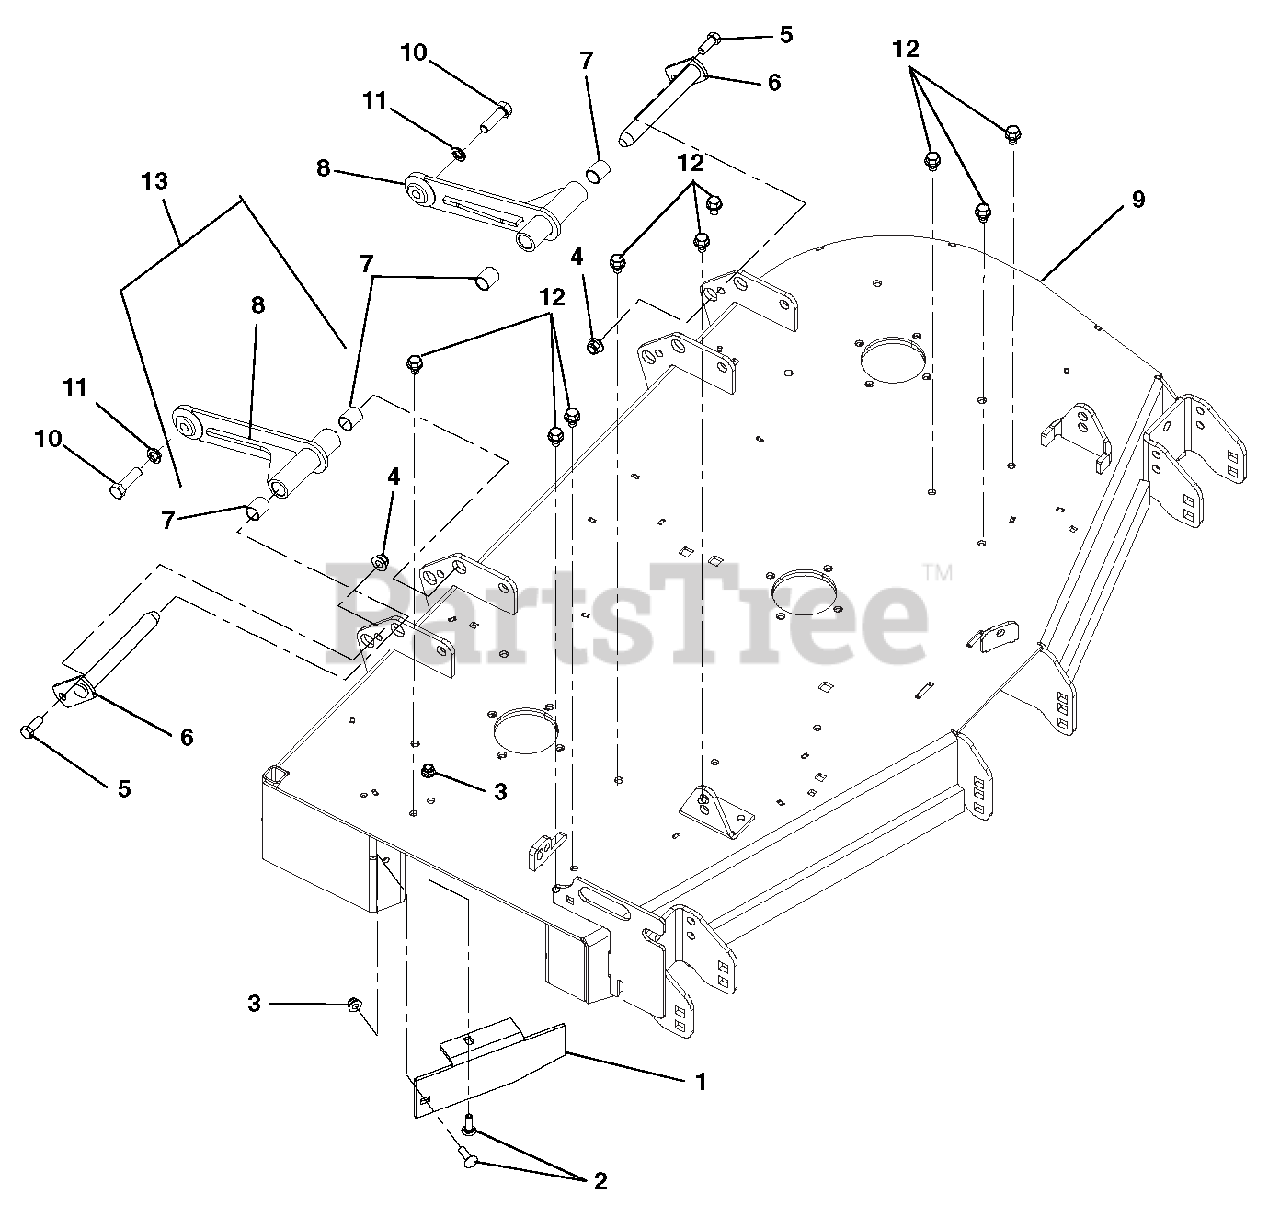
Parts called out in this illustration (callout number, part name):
1	44"-48" SIDE DISCH BAFFLE -RED
2	@BLT-RDHDSQNK .31-18X1.00 G5YZ
3	@NUT-LK-NYL-FLG .31-18 YWZC
4	@NUT-LK-NYL-FLG .38-16 YWZC
5	@BLT-HEX .38-16X1.00 GR5 YWZC
6	WELDMENT, MOWER MTG. PIN
7	BRG, .750 X .875 X 1.000
8	DECK PUSHER ARM WMT - BLACK
9	48" SIDE DISCHARGE DECK - RED
10	@BLT-HEX .50-13X1.75 GR5 YWZC
11	@WSHR-LK .50X.125 REG YWZC
12	@SCR-TAP .38-16X.50 HWH TR YWZ
13	DECK PUSHER ARM ASSEMBLY
